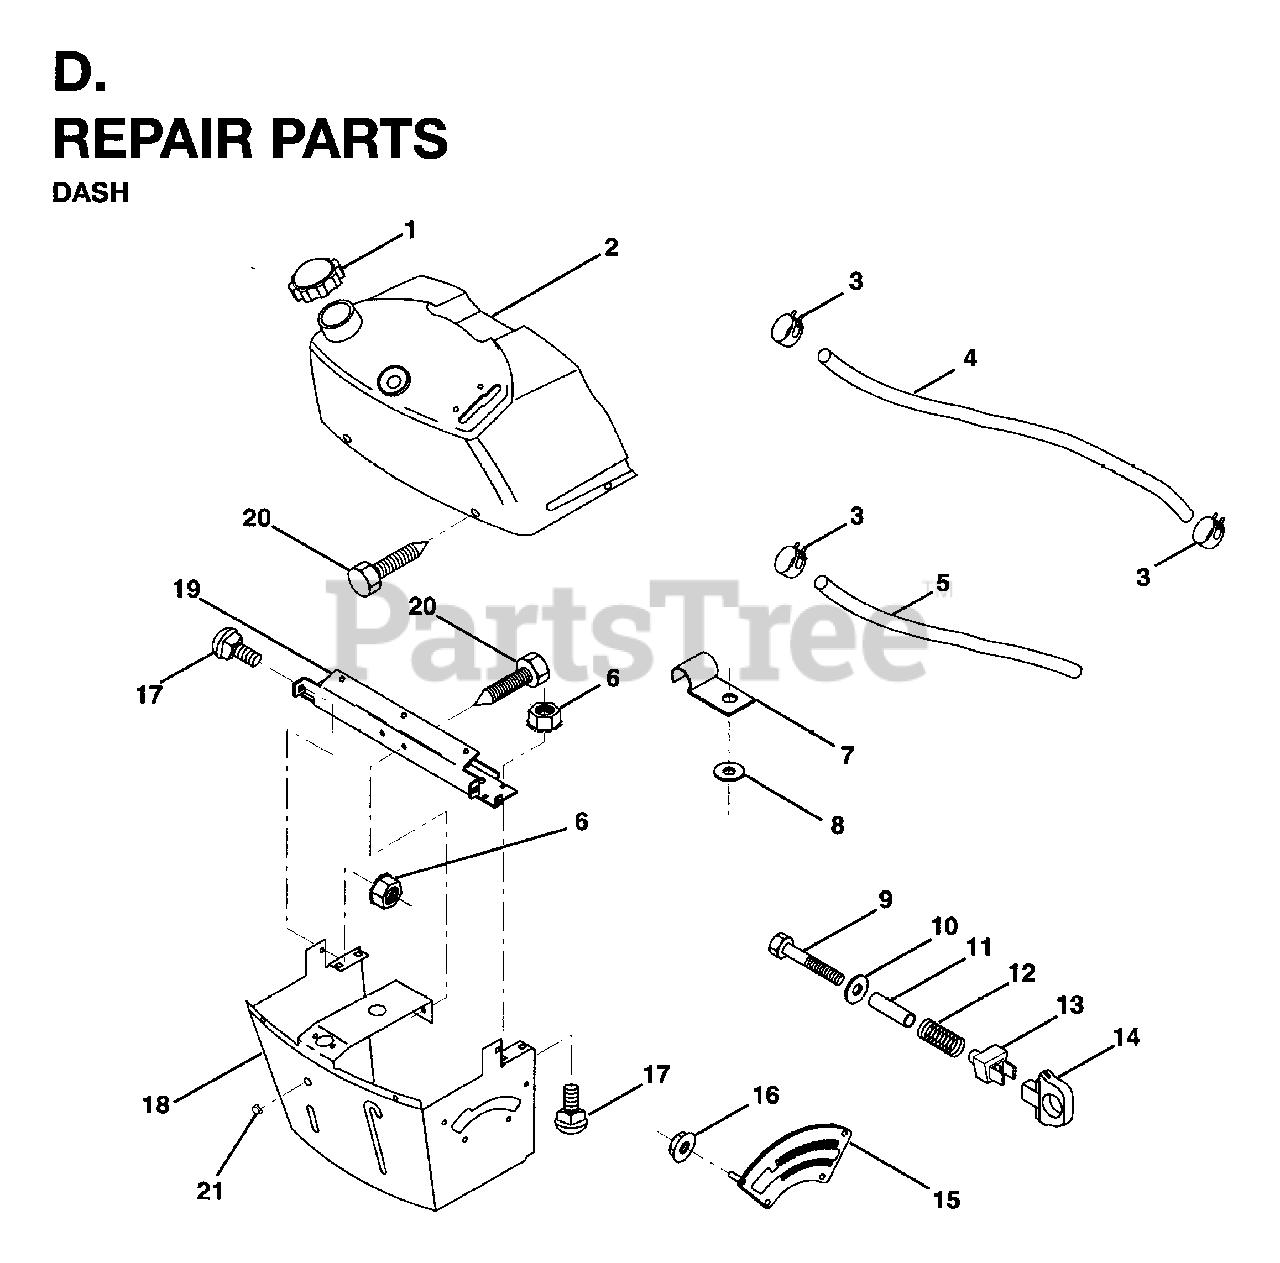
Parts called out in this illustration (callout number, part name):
3	HOSE CLAMP
4	FUEL LINE
5	FUEL LINE T
6	NUT.CROWNLOCK.1/4
7	CLIP T
8	WASHER - 26X6.5X1.6
9	BOLT HEX FIN 1/4-20X1 3/4
10	WASHER
11	SPACER SPLIT
12	SPRING.COMPRESSION
13	KNOB HGT RETAINER
14	KNOB
15	ADJUSTER QUAD
18	SUPT ASSY DASH
19	CROSS BRACE
21	PLUG DOME
